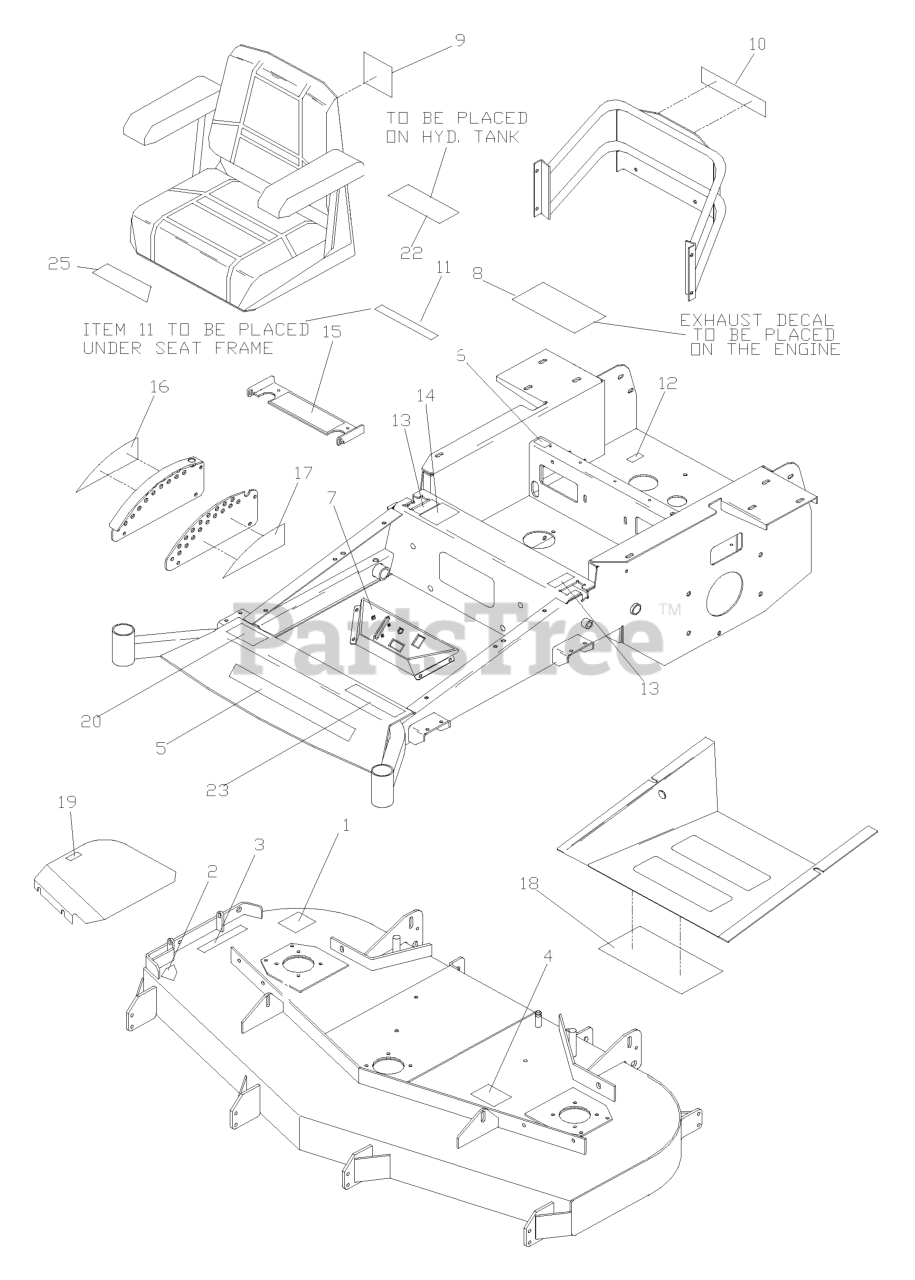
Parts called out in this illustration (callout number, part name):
1	DECAL, ANTI SCALP
2	DECAL, DANGER
3	DECAL, EURO SEVERING
4	DECAL, BELT ROUTING
5	DECAL, HUSQVARNA 17.5"
6	FUEL VALVE DECAL
6	DECAL, FUEL VALVE
7	DECAL, CONSOLE
8	DECAL, EXHAUST
9	DECAL, CROWN H
10	DECAL, HUSQVARNA LOGO 9.25"
11	EURO DECAL-BATTERY WARNIN6
12	DECAL, PROP. 65
13	DECAL, MOTION CONTROL
14	DECAL,THROWN OBJECT
15	DECAL, EURO WARNING
16	DECAL, HEIGHT
17	DECAL, HEIGHT
18	DECAL, SERVICE
19	DECAL, NO STEP
20	DECAL, NASCAR
21	DECAL - ZTH7226EFI
21	DECAL, ZTH5221
21	DECAL, ZTH5223
21	DECAL, ZTH5223L
21	DECAL, ZTH5225
21	DECAL, ZTH6123L
21	DECAL - ZTH6123
21	DECAL, ZTH6125
22	DECAL, MOBIL 1
23	DECAL, XP SERIES
24	DECAL, BELT DRIVE
25	DECAL, MICH SEAT
